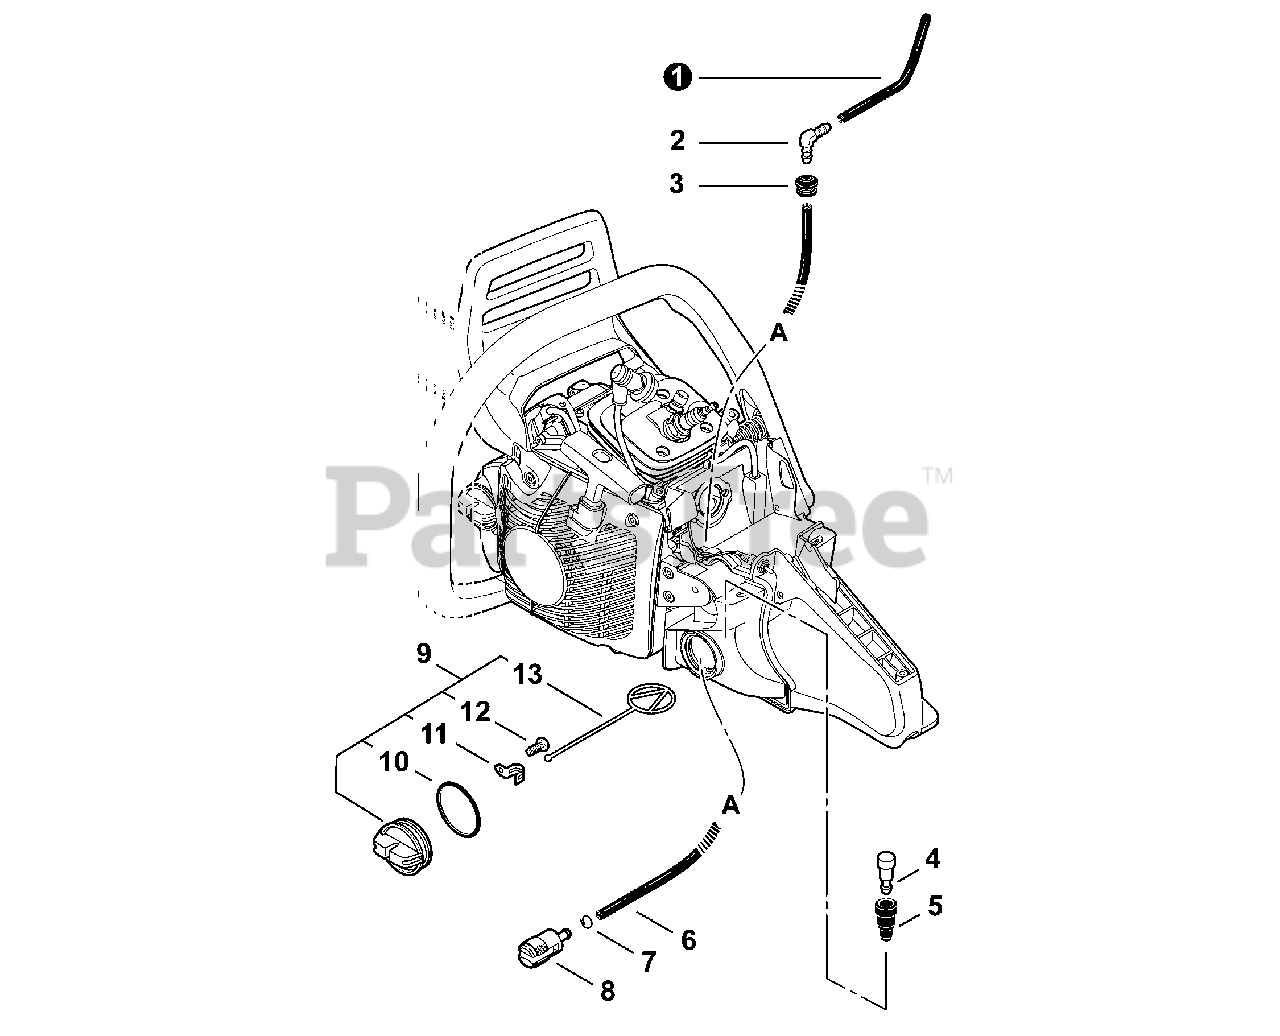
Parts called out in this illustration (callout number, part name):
1	PIPE, FUEL 3×6×135L
2	CONNECTOR, PIPE
3	GROMMET
4	VENT ASSY
5	GROMMET, VENT
6	PIPE, FUEL 3×5×120 BLACK
7	CLIP Ø6
8	FILTER, FUEL
9	CAP ASSY, FUEL
10	O-RING 29
11	RETAINER, CONNECTOR
12	SCREW, TAPPING 3×8
13	CONNECTOR, CAP L= 60 MM
